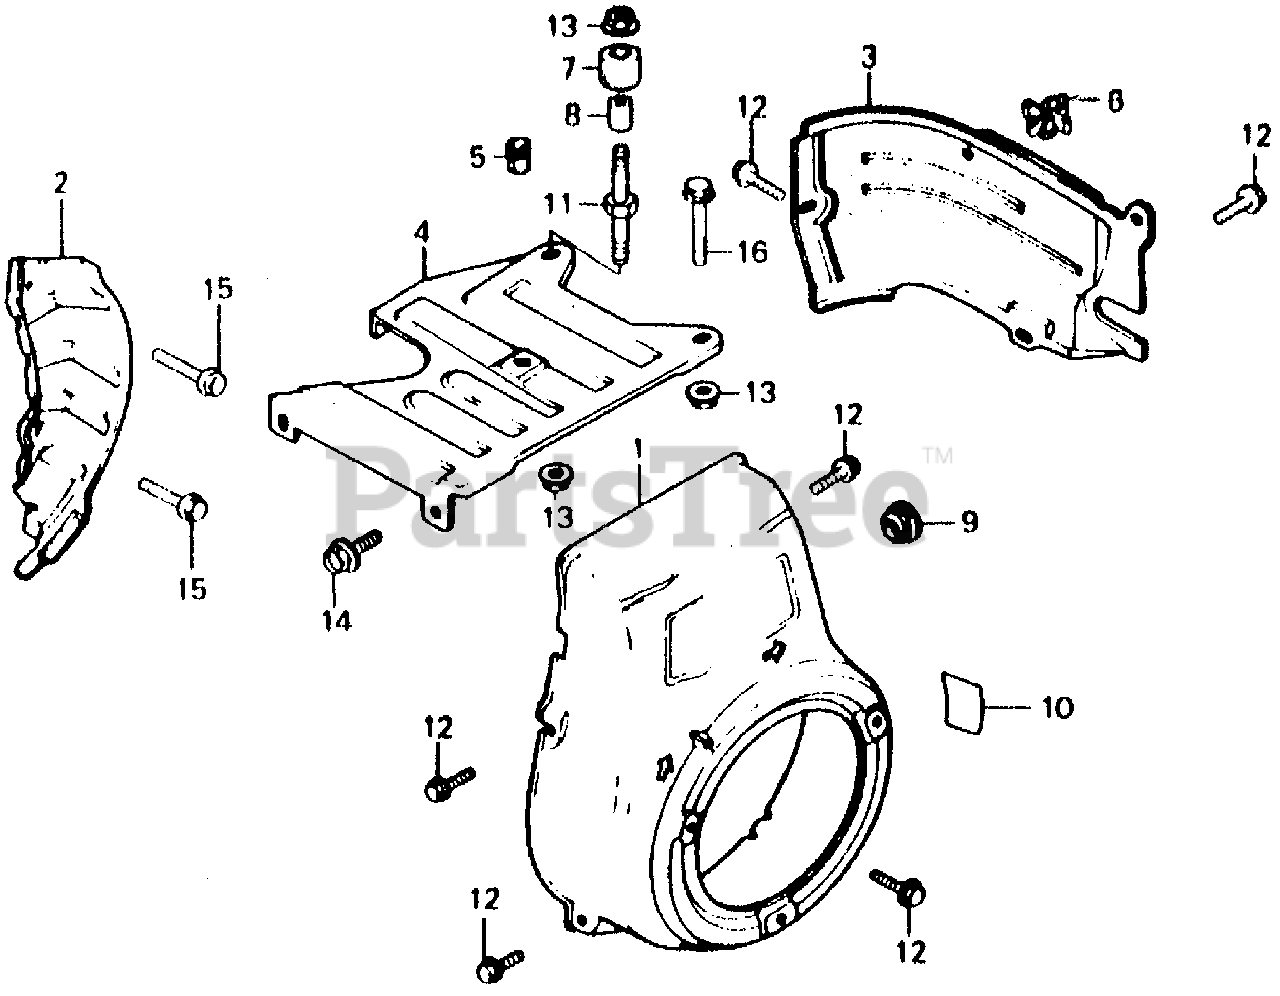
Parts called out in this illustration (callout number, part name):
1	COVER, FAN *R8* (BRIGHT RED)
2	PLATE, SIDE
4	COVER, TOP
5	GROMMET, COVER
6	CLIP, IGNITION WIRE (8MM)
7	RUBBER, STOPPER (NOT AVAILABLE)
8	COLLAR, DISTANCE
9	GROMMET, DRAIN HOLE
10	MARK, OIL CAUTION
11	BOLT, SPECIAL HEX.
12	BOLT, FLANGE (6X12) (CT200)
13	NUT, FLANGE (8MM)
14	BOLT, FLANGE (8X16)
15	BOLT, FLANGE (8X20)
16	BOLT, FLANGE (8X28)
